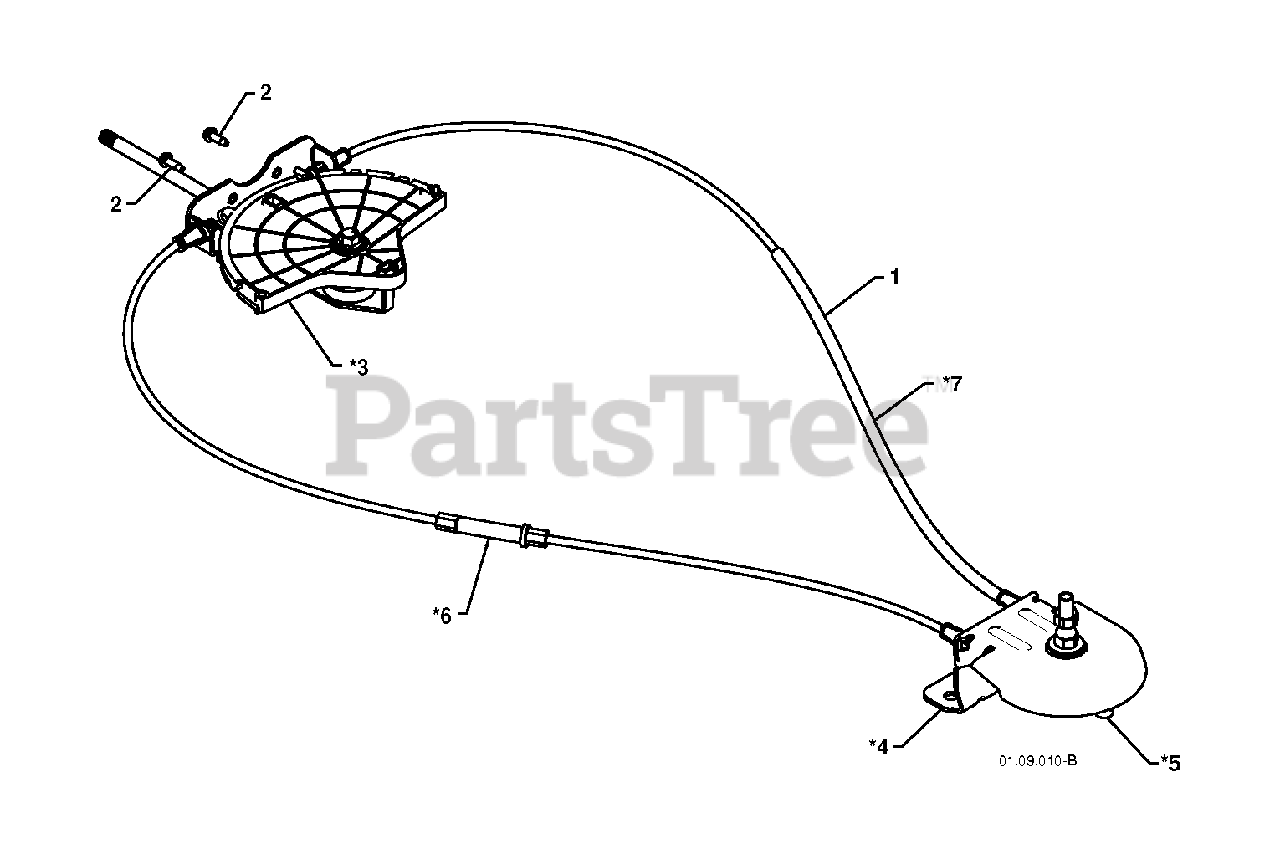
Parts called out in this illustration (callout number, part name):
1	LEVER/CABLE.ASM.ROTATOR
2	SCREW #10-24 X 5/8
3	CHUTE.ROT.HEAD.SERVICE
4	SNOW.PIVOT.BRKT.BLK.SERVICE
5	SNOW.PIVOT.PULLY
6	SNOW.CBL.ASM.ADJ.SERVICE(74)
7	SNOW.CBL.ASM.SERVICE(428272)
